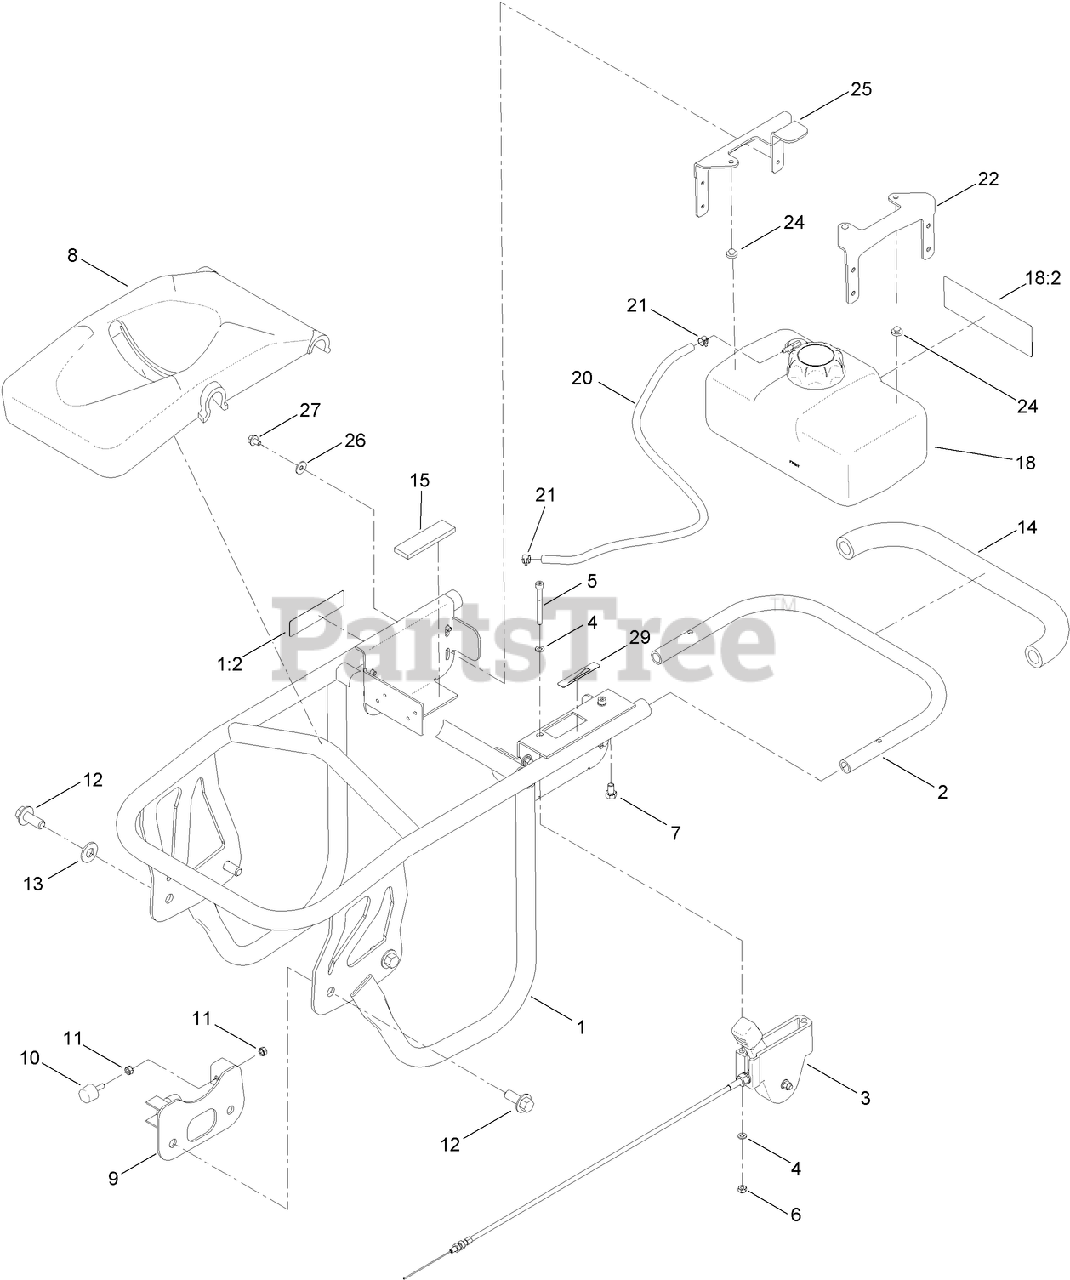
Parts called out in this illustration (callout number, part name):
1	HANDLE ASM
1:2	DECAL-ARRESTER, SPARK
2	HANDLE-RAMMER
3	THROTTLE LEVER ASM
4	WASHER-FLAT
5	SCREW-HSH
6	NUT-LOCK
7	SCREW-HWH
8	COVER-ENGINE
9	STOPPER
10	MOUNT-SHOCK
11	NUT-HEX
12	SCREW-HHF
13	WASHER
14	GRIP-CUSHION, HANDLE
15	PAD-TANK, FUEL
18	1 GALLON FUEL TANK ASM
18:2	DECAL-WARNING
20	HOSE-FUEL
21	CLAMP-HOSE
22	BRACKET-TOP, FUEL TANK
24	BUMPER-RUBBER
25	GUARD-FUEL TANK, TOP
26	WASHER-FLAT
27	SCREW-HHF
29	DECAL-THROTTLE
